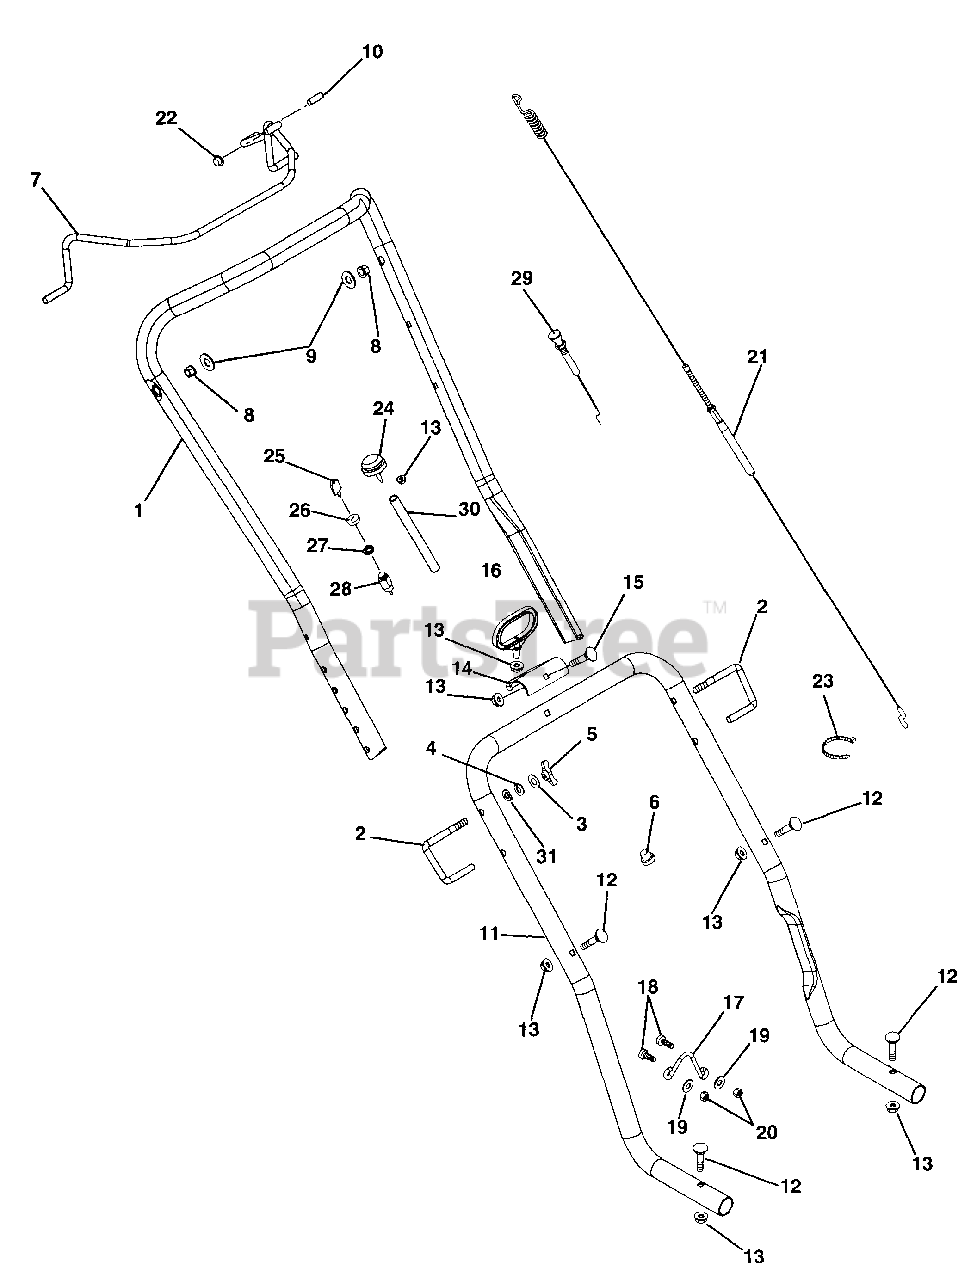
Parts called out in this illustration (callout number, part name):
1	HANDLEBAR, UPPER
2	J BOLT .31-18
3	WSHR-FL-STL .328X.875X.062YWZC
4	WSHR-LK .312X.097 HVY YWZC
5	KNOB - WING .312-18 UNC
6	PLUG-HOLE .50 DIA
7	BAIL SS LF
8	BSHG-FLG .325X.444X.440X.560
9	@WSHR-FL-STL.344X.688X.065YWZC
10	CAP, VINYL, .25 ID
11	HANDLEBAR, LOWER
12	BLT-RDHDSQNK .25-20X1.75 G5YZ
13	NUT-LK-FLG .250-20 PL BLK
14	BRKT-STARTER HANDLE
15	BLT-RDHDSQNK .25-20X1.50 PL BL
16	HANDLE, RECOIL START
17	GUIDE-ROPE
18	@SCR-MCH 10-24X.75 HWH YWZC
19	@WSHR-FL-STL.219X.50X.049 YWZC
20	@NUT-LK-NYL 10-24 W/INSRT YWZC
21	CABLE-CLUTCH CONTROL
22	PUSH NUT, .25
23	CABLE TIE LG 5-1/2
24	PRIMER ASSY
25	KEY -W/CAP
26	CAP - IGNITION SWITCH
27	NUT-PANEL .625-32 GRECO
28	KEY SWITCH ASSEMBLY
29	CONTROL-CHOKE 5 HP
30	LINE-PRIMER
31	WASHER,SADDLE-.320 X.937 X.062
